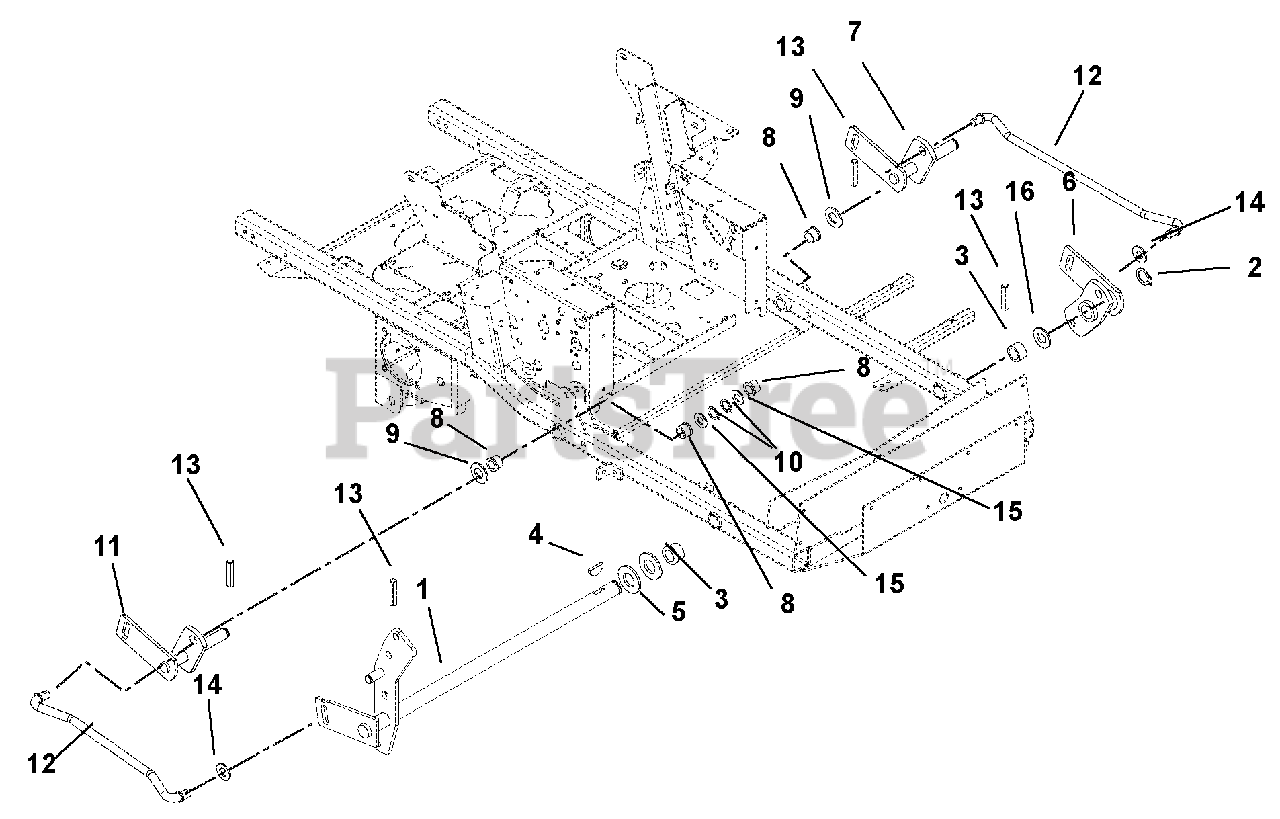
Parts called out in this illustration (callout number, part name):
1	Lift, Hydraulic Mower
2	Ring, Retaining External 1.00 x .078
3	Bushing, 1.00 x 1.12 x .75 x 1.375
4	Key, Woodruff .25 x 1.00
5	Washer, Flat Steel 1.062 x 2.00 x .134
6	Weldment, Lift Arm Front
7	Weldment, Rear Lift Arm Left Hand
8	Bushing, Flange Nylon .762 x 1.00 x .58 x 1.48
9	Washer, Hardened Steel .758 x 1.23 x .031
10	Ring, Retaining External .689 x .077
11	Weldment, Right Hand Rear Lift Arm
12	Rod, Lift Assist
13	Pin, Roll .250 x 1.25 Stainless Steel
14	Washer, Flat Steel .630 x 1.25 x .062
15	Washer, Flat Steel .812 x 1.50 x .135
16	Washer, Hardened Thrust 1.00 x 1.55 x .03
